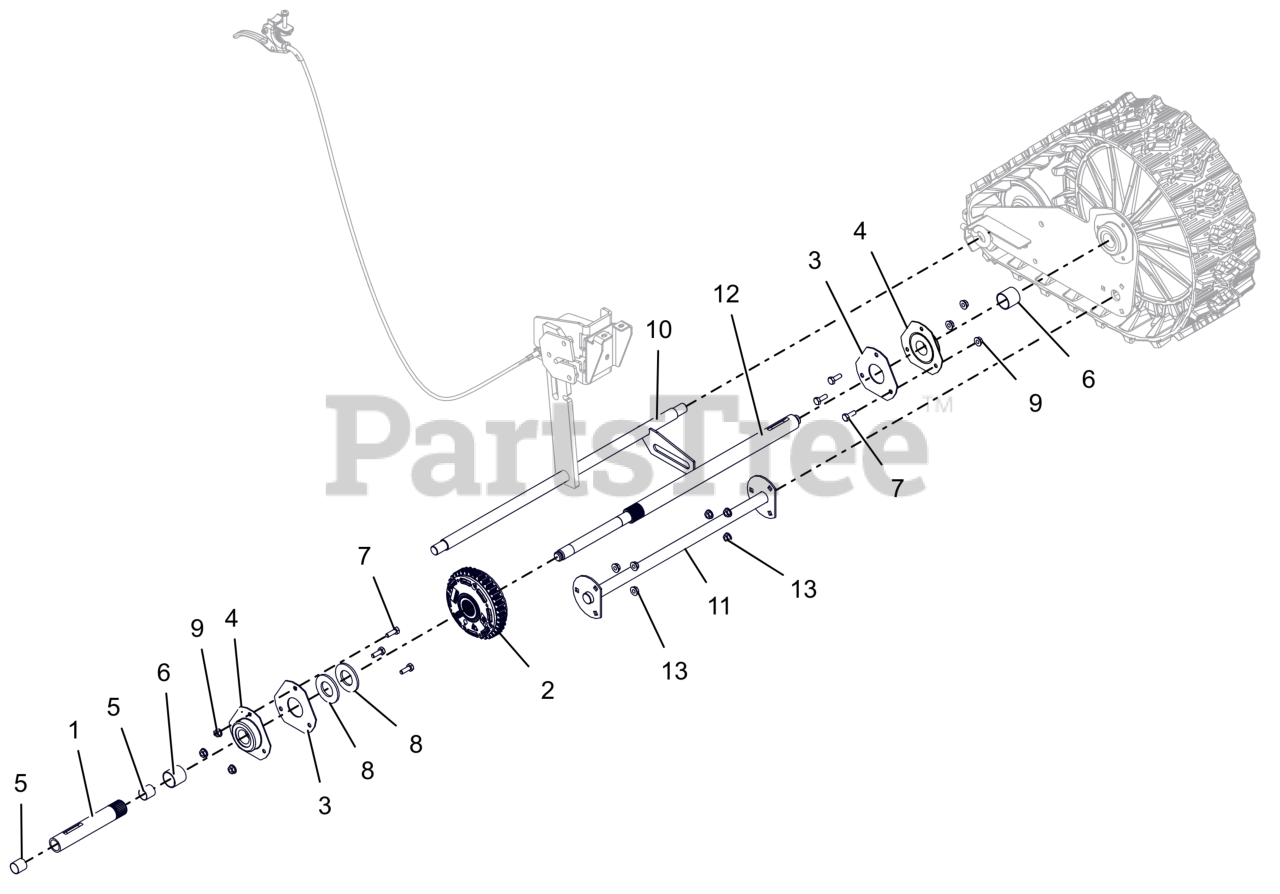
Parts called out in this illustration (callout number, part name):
1	AXLE, SHORT-W/BUSHINGS
2	DIFFERENTIAL, AUTOMATIC
3	PLATE, BEARING SPACER
4	BRG-FLG 1.003/1.000 3 BOLT
5	BSHG-SLV .706X.764X.75 BRZ
6	BSHG-SLV, 1.012X1.125X1.00
7	BLT, HEX .25-20X.75 G5 ZCC
8	WSHR, FLT 1.062X2.000X.134 ZCC
9	NUT-LK-CTR-FLG .25-20 ZC120
10	AXLE, REAR-BWT WLDMT
11	SUPPORT, FRONT-BWT
12	AXLE, LONG-TRACK DIFFERENTIAL
13	NUT-LK-TOP-FLG .250-20 GF ZCC
